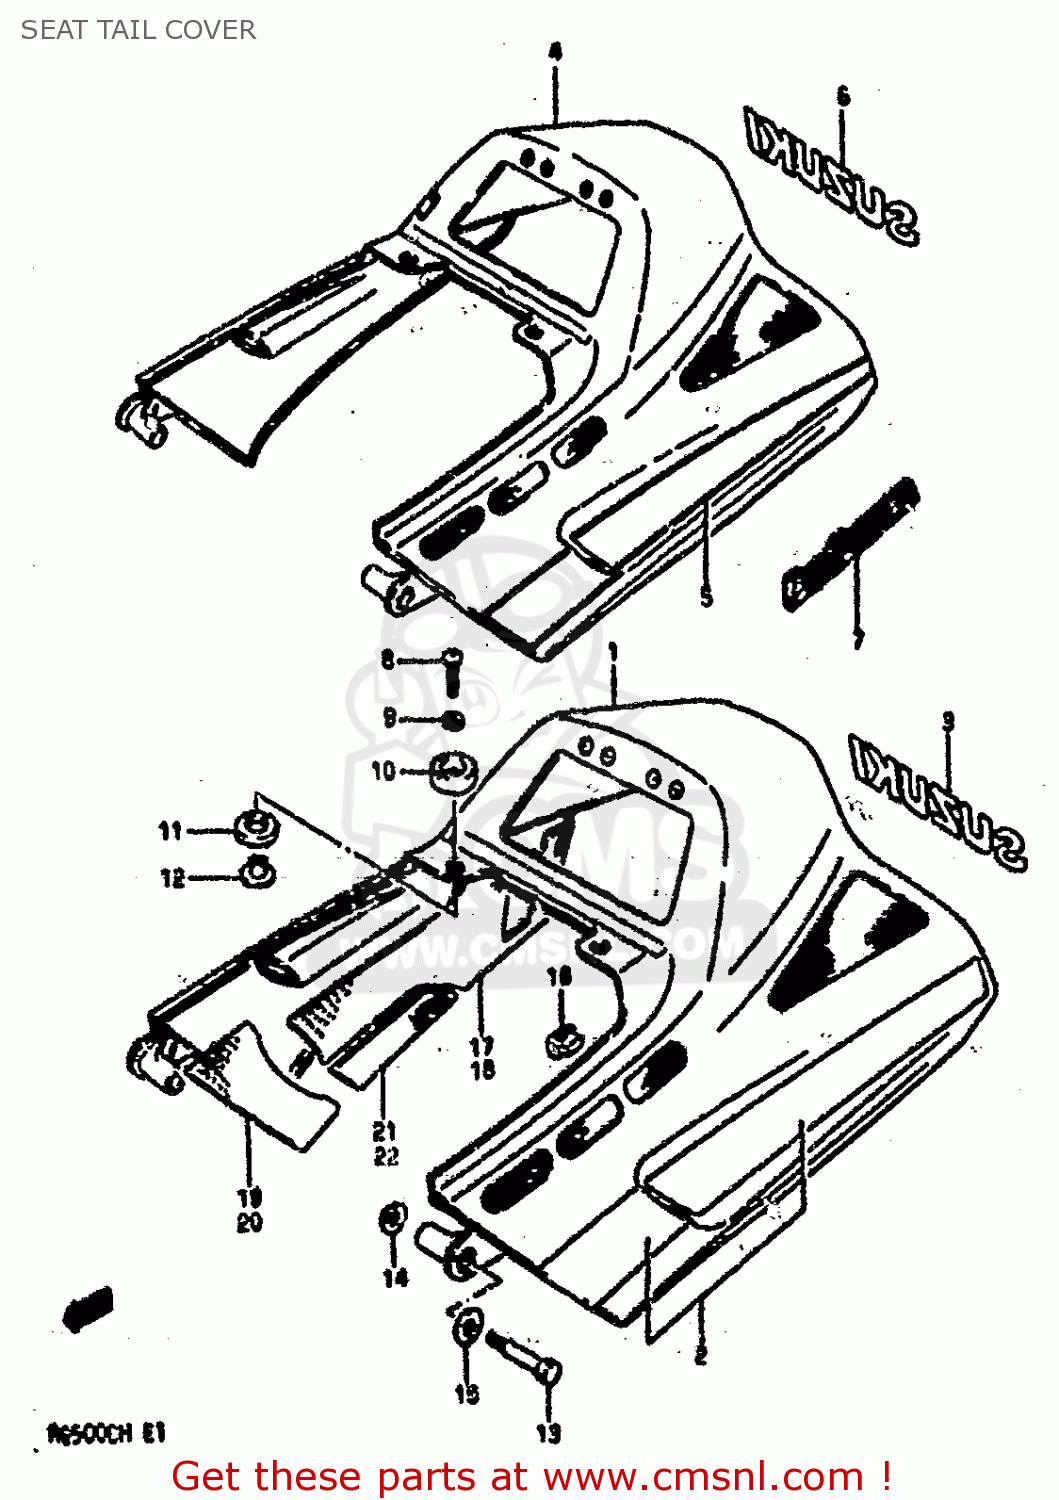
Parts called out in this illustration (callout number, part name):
1	COVER,SEAT TAIL
2	TAPE SET,SEAT TAIL (BLUE)
3	EMBLEM,COVER SEAT TAIL
4	COVER,SEAT TAIL
5	TAPE SET,SEAT TAIL
6	EMBLEM
7	EMBLEM
8	SCREW
9	WASHER
10	CUSHION,TAIL COVER UPR
11	CUSHION,TAIL COVER LWR
12	SPACER,SEAT TAIL COVER
13	BOLT
14	WASHER(6.5X16X1.2)
15	WASHER(9X22X1.6)
16	CUSHION RADI C
17	HEAT SHIELD,CENTER RH
18	HEAT SHIELD,CENTER LH
19	HEAT SHIELD,FRONT RH
20	HEAT SHIELD,FRONT LH
21	HEAT SHIELD,LOWER RH
22	HEAT SHIELD,LOWER LH
